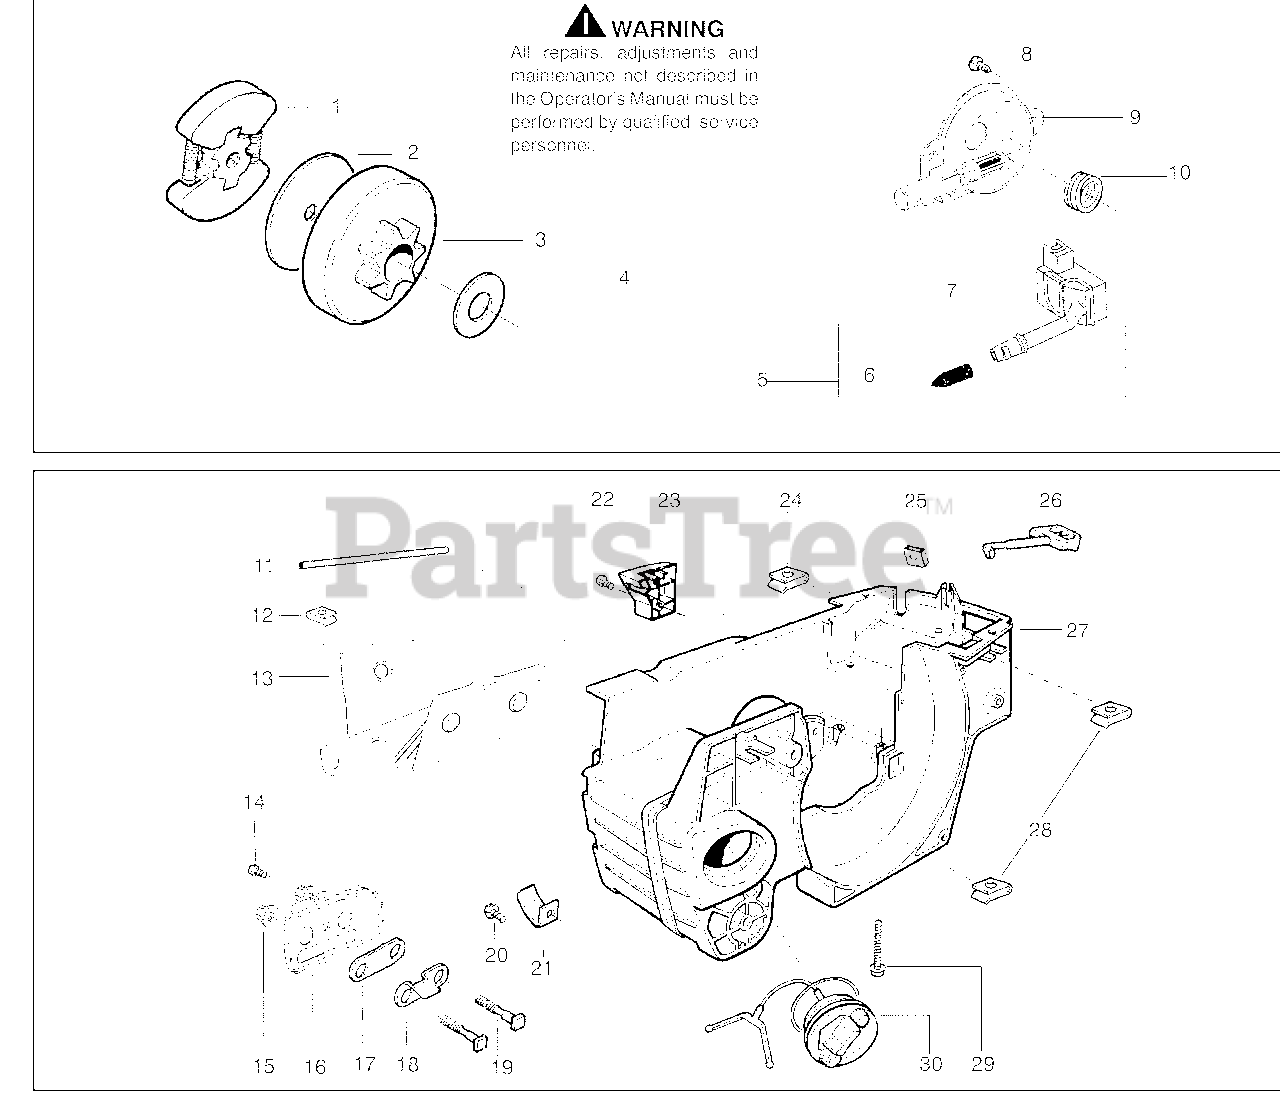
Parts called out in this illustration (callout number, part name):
1	Assy--Clutch
2	Washer--Clutch
3	Assy--Clutch Drum w/Bearing
4	Washer--Thrust
5	Assy--Oil pickup and screen
6	Filter--Oil
7	Assy--Pickup
9	Assy--Oil Pump
10	Worm Gear--Oil Pump
11	Tube--Oil Vent
12	Clip--Retainer
13	Shield--Heat
14	Screw
16	Plate--Bar
18	Plate--Bar Stud
21	Chain Catcher
24	Nut--Type "U" Speed
26	Lever--Choke
27	Kit -- Chassis Ass’y.
28	Nut--Type "U" Speed
30	Assy.-- Oil Tank Cap
